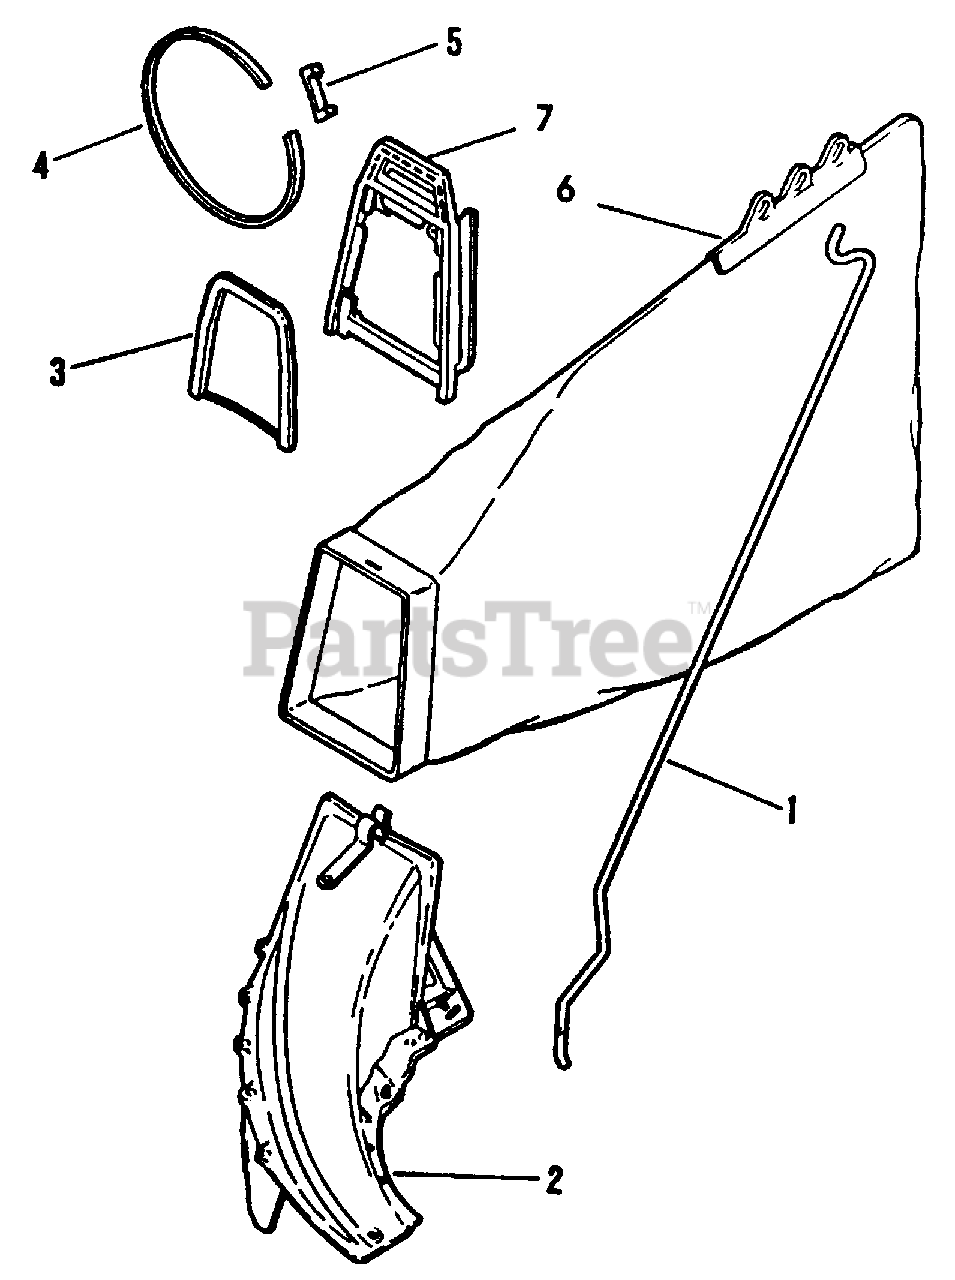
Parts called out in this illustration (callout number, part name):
1	Bag Support Rod
2	Chute Kit
3	Chute Brace
4	Strap and Lock
5	Strap Lock
6	Grass Bag
7	Chute Adaptor
